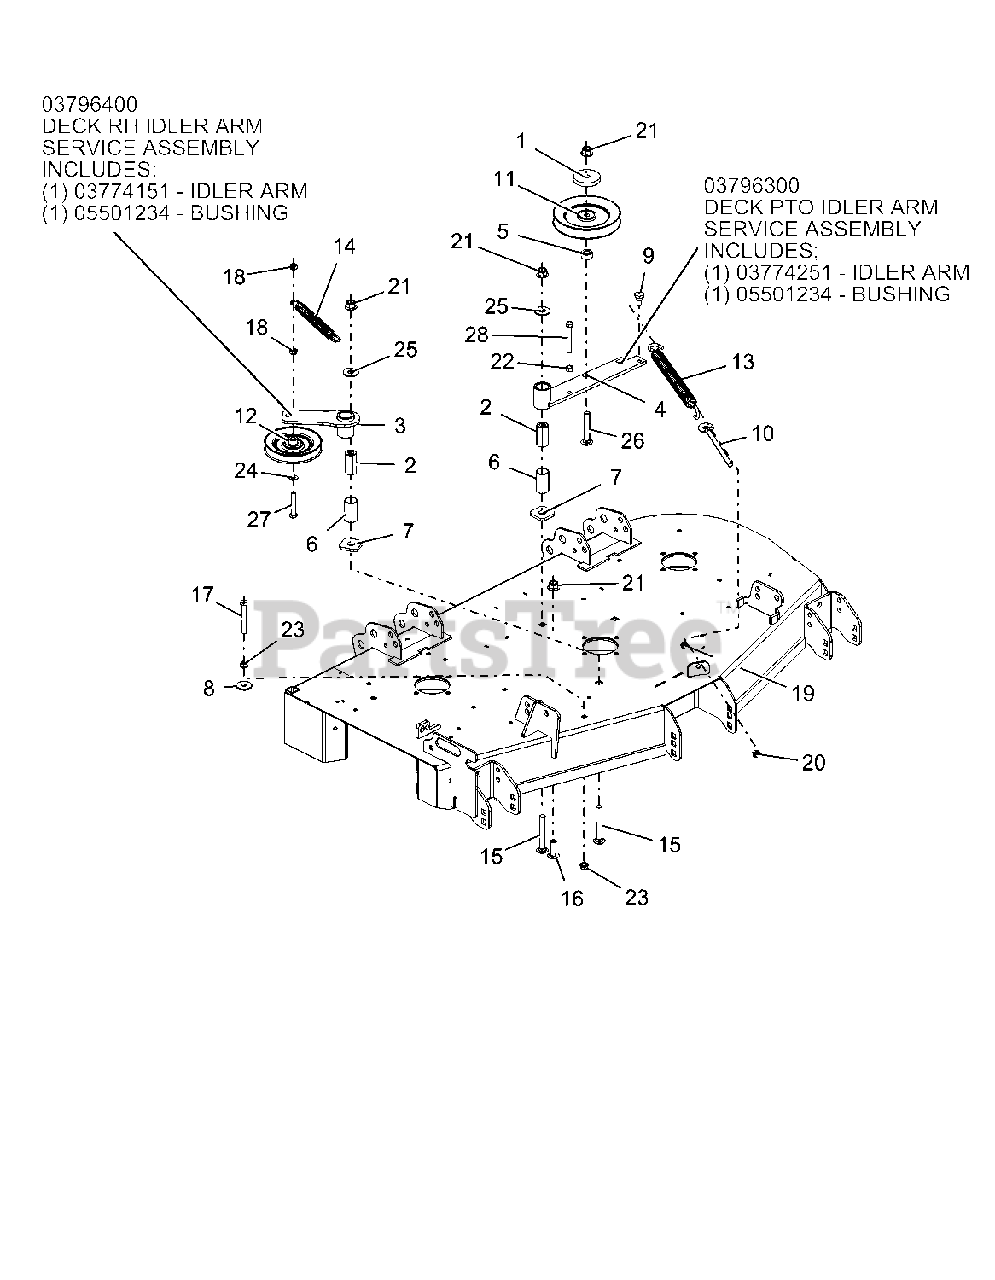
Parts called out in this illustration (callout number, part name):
1	CAP, IDLER BEARING SEALING
2	BSHG, SPCR .502X.997X2.03
3	WMT, IDLER PIVOT ARM-BLACK
3	DECK RH IDLER ARM SERVICE ASSEMBLY
3	IDLER ARM
3	BUSHING
4	WMT, IDLER PIVOT ARM-BLACK
4	DECK PTO IDLER ARM SERVICE ASSEMBLY
4	IDLER ARM
4	BUSHING
5	BSHG, SPCR .502 X .997.50 PM
6	BSHG, 1.00x1.125x1.947
7	WSHR, -FLT.640X1.75X.250
8	WSHR-FL-STL .406X1.375X.135 YZ
9	BLT, SHLDR EP .38-16X.30 HEX YZ
10	BOLT, .38-16X6.00 .62 DIA EYE
11	SHEAVE, .50" ID X 6.00" OD V-IDLER
12	IDLER, V-5.00" W/.69 STANDOFF
13	SPRG, EXTENSION
14	SPRG, EXTENSION .120X.845X6.55 WLD
15	BLT-RDHDSQNK .50-13X3.50 G5 Y
16	BLT-RDHDSQSHNK .50-13X1.50 YWZC
17	BLT-HEX .38-16X3.00 GR5 YWZC
18	NUT-LK-CTR .38-16 YWZC
19	NUT, JAM .375-16 YWZC
20	NUT-LK-CTR-JAM .375-16 YWZC
21	NUT-LK-NYL-FLG .50-13 YWZC
22	NUT-HEX .38-16 YWZC
23	@NUT-SPNLK-FLG .375-16 YWZC
24	WSHR-FL-STL.406X.812X.065 YWZ
25	WSHR-FL-STL.563X1.38X.109YWZC
26	BLT-RDHDSQNK .50-13X3.00 G5 Y
27	BLT-HEX .38-16X2.25 GR5 YWZC
28	BLT-HEX .38-16X2.75 GR8 YWZC
